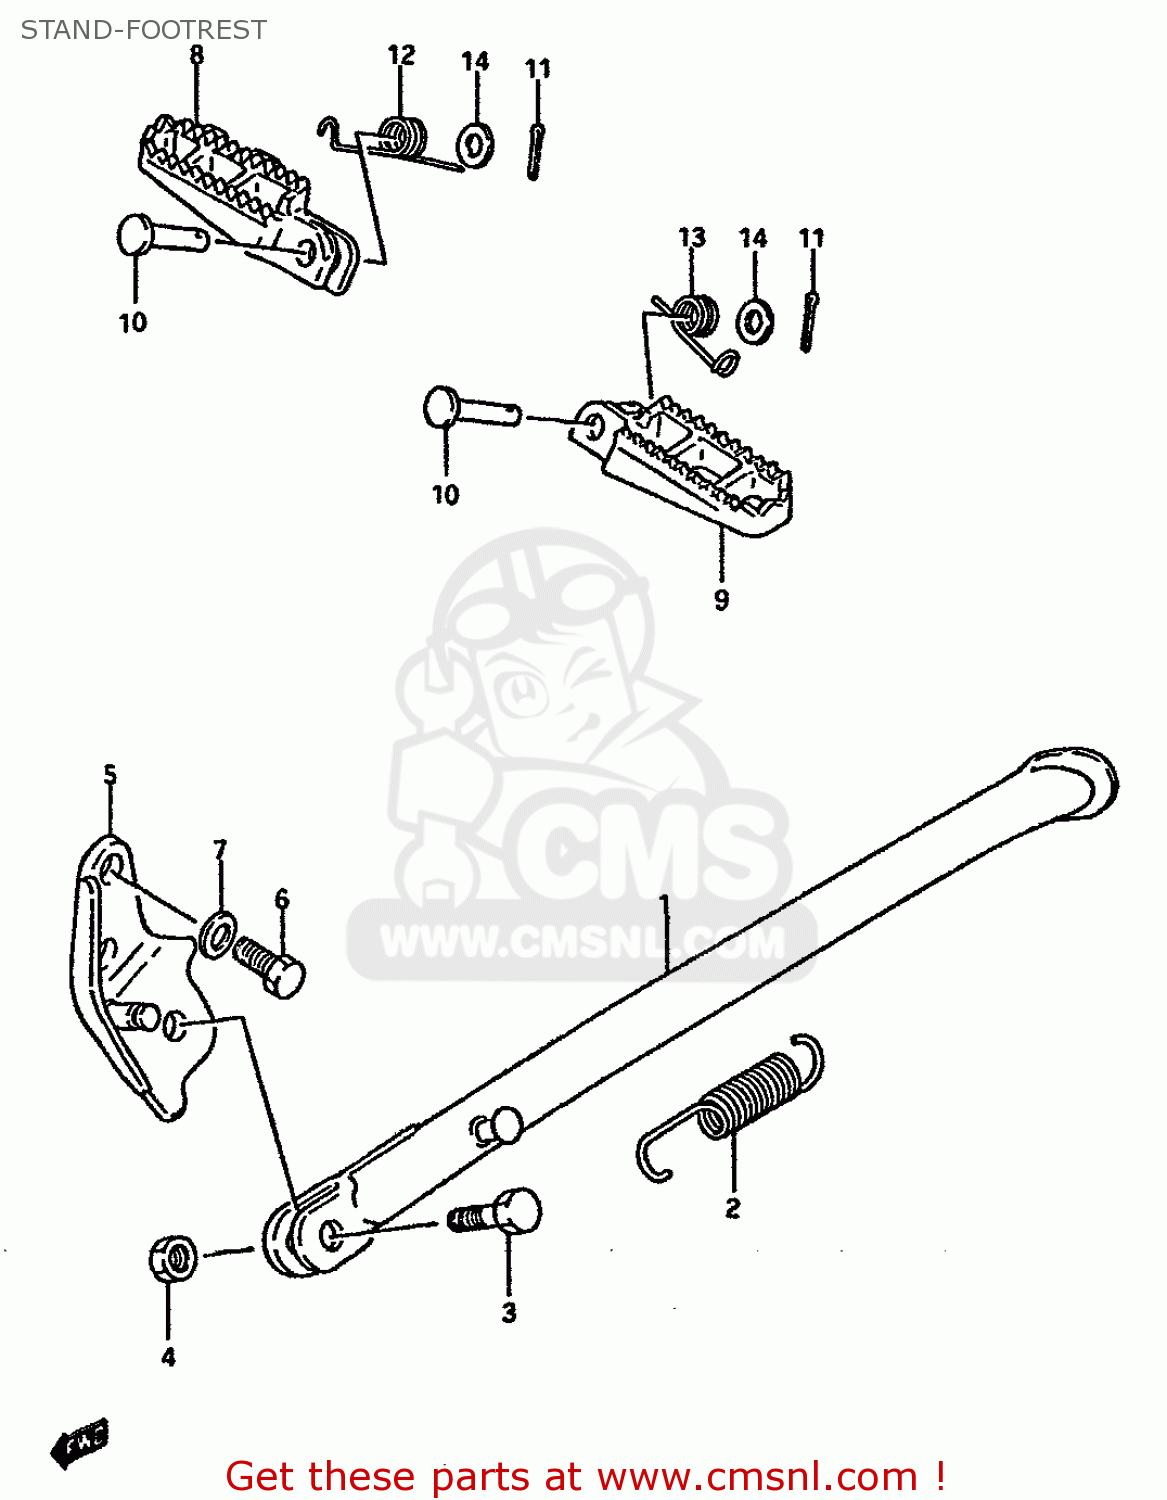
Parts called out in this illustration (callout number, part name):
1	STAND,SIDE
2	SPRING
3	BOLT(10X30)
4	NUT
5	BRACKET,SIDE STAND
6	BOLT(10X19)
7	WASHER,LOCK,10
8	FOOTREST
9	FOOTREST
10	PIN
11	PIN 20X20
12	SPRING
13	SPRING
14	WASHER
